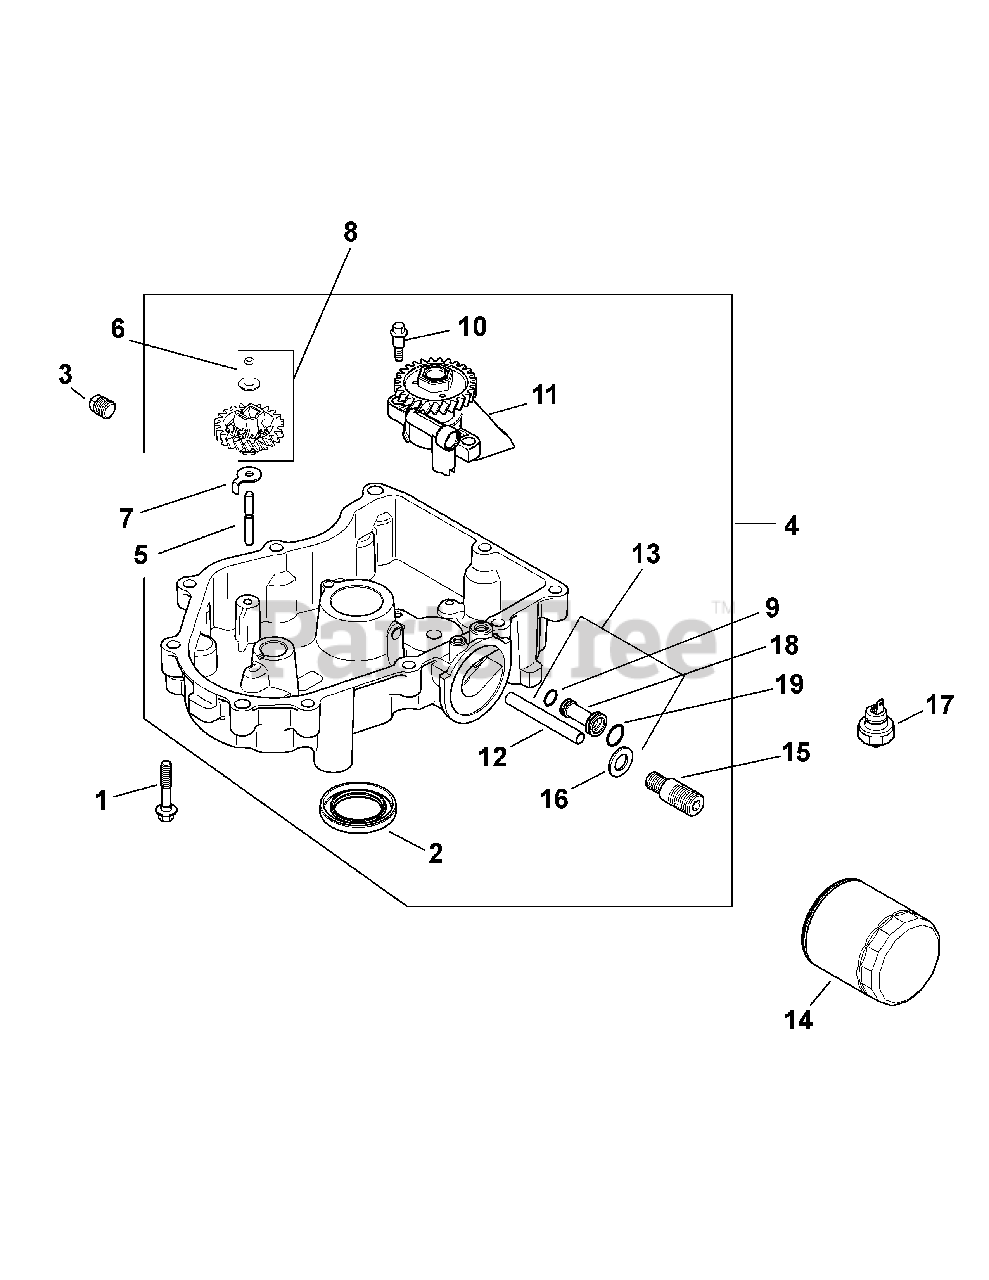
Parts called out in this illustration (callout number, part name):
1	Flange Screw, M8 x 1.25 x 45
2	Oil Seal, 2.38 x 1.45
3	Square Head Pipe Plug, 3/8
4	Oil Pan Assembly
5	Governor Gear Shaft
6	Governor Regulating Pin
8	Governor Gear Kit
9	Oil Pick-Up O-Ring
11	Oil Pump Assembly
12	Oil Feed Tube (Filter to Oil Pan)
13	Oil Feed Tube Assembly
15	Oil Filter Nipple
17	Oil Pressure Switch
18	Oil Feed Tube
